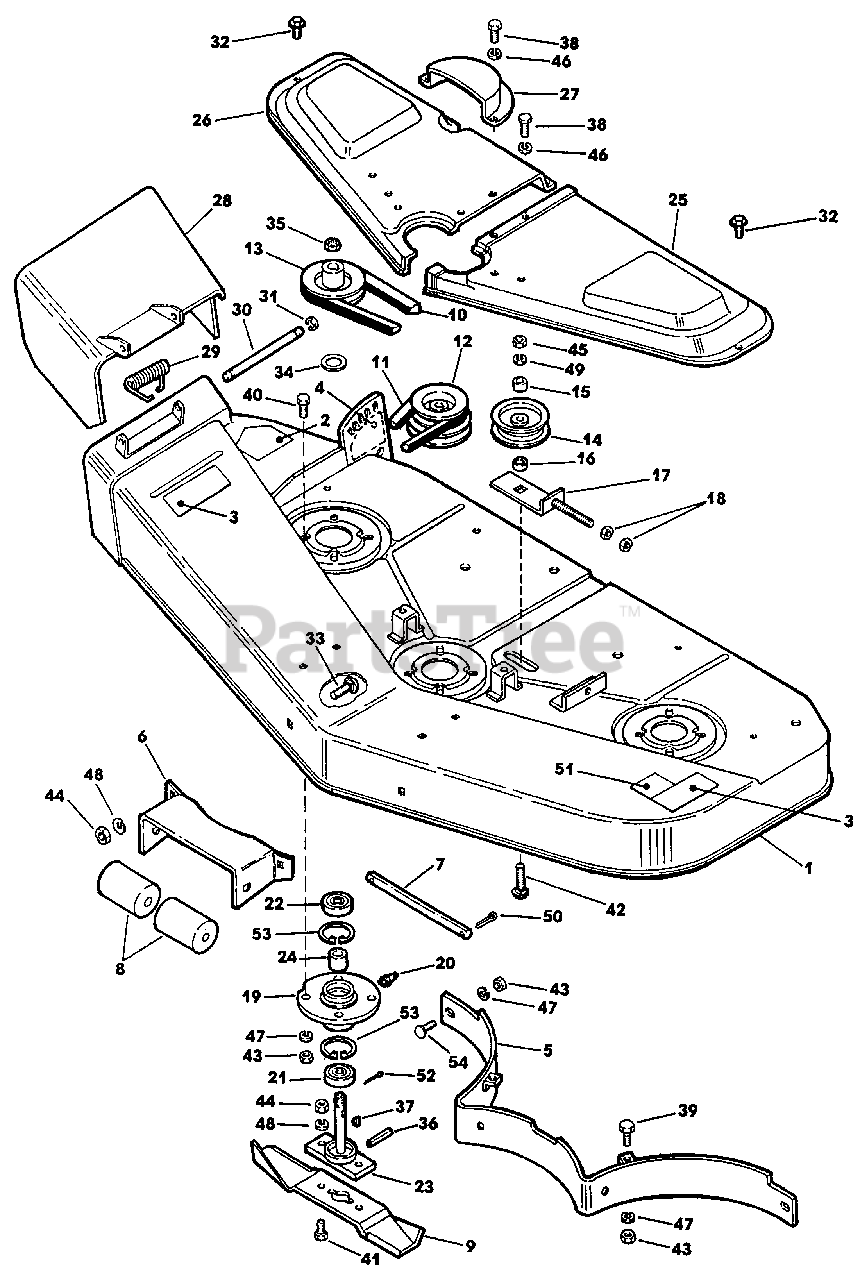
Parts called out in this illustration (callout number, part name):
1	Cutter Housing & Decal Ass'y (42")
2	Decal-Cut Finger
3	Decal-Danger
4	Decal-Cutting Height
5	Baffle (42" Only)
5	Baffle (48" Only)
6	Bracket, Roller
7	Shaft, Roller
8	Roller
9	Blade (42" Only)
9	Blade, Center (48" Only)
9	Blade, Outer (48" Only)
10	V-Belt, Deck (42" Only)
11	V-Belt, Drive
12	Pulley, Drive (42" Only)
13	Pulley, Blade Spindle
14	Pulley, Idler
15	Spacer
16	Washer
17	Belt Tightener
18	Nut, Hex
19	Spindle Housing
20	Grease Fitting
21	Bearing, Lower
22	Bearing, Upper
23	Spindle
24	Sleeve
25	Cover Ass'y-L.H. (42" Only)
26	Cover Ass'y-R.H. (42" Only)
27	Guard, Drive Belt
28	Chute Extension
29	Spring, Chute Extension
30	Shaft, Chute Extension
31	E-Ring
32	Thread Forming Screw, Hex Hd
33	Bolt, Carriage
34	Spacer
35	Nut, Hex Slotted
36	Pin, Roll
37	Key, Woodruff
38	Cap Screw, Hex Hd
39	Cap Screw, Hex Hd
40	Cap Screw, Hex Hd.
41	Cap Screw, Hex Hd
42	Bolt, Carriage
43	Nut, Hex
43	Retaining Ring
44	Nut,Hex
45	Nut, Hex Jam
46	Washer, Spring Lock
47	Washer, Spring Lock
48	Washer, Spring Lock
49	Washer, Spring Lock
50	Pin, Cotter
51	Decal-42"
52	Pin, Cotter
54	Carriage Bolt
